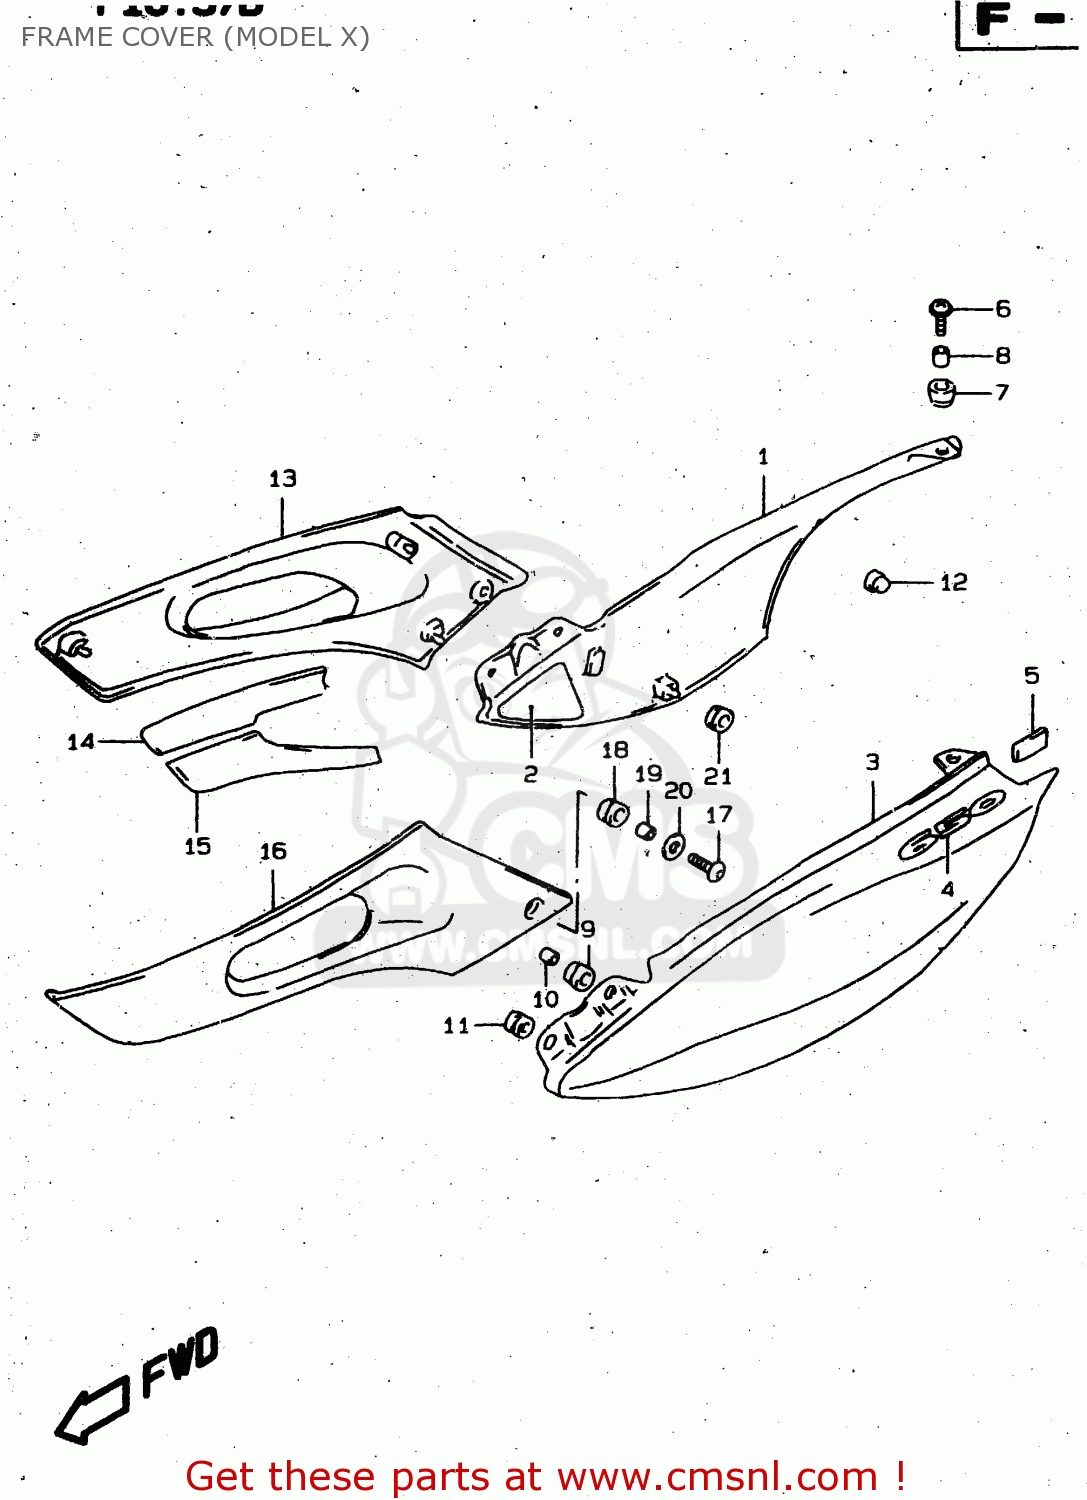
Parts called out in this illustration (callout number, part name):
1	COVER, FRAME RH (BLUE)
2	SHIELD,FRAME COVER,R
3	COVER,FRAME,L(BLUE)
4	EMBLEM,FRAME COVER
5	CUSHION,FR FENDER
6	SCREW(6X20)
7	CUSHION
8	SPACER(6.5X10X9.4)
9	CUSHION
10	SPACER(6.5X9X9)
11	CUSHION
12	CUSHION
13	COVER,FRAME FR,R
14	SHIELD, FRONT RH UPPER
15	SHIELD, FRONT RH LOWER
16	COVER,FRAME FR,L
17	SCREW(6X30)
18	CUSHION
19	SPACER(6.5X9X9)
20	WASHER(6.5X18X1.6)
21	CUSHION
